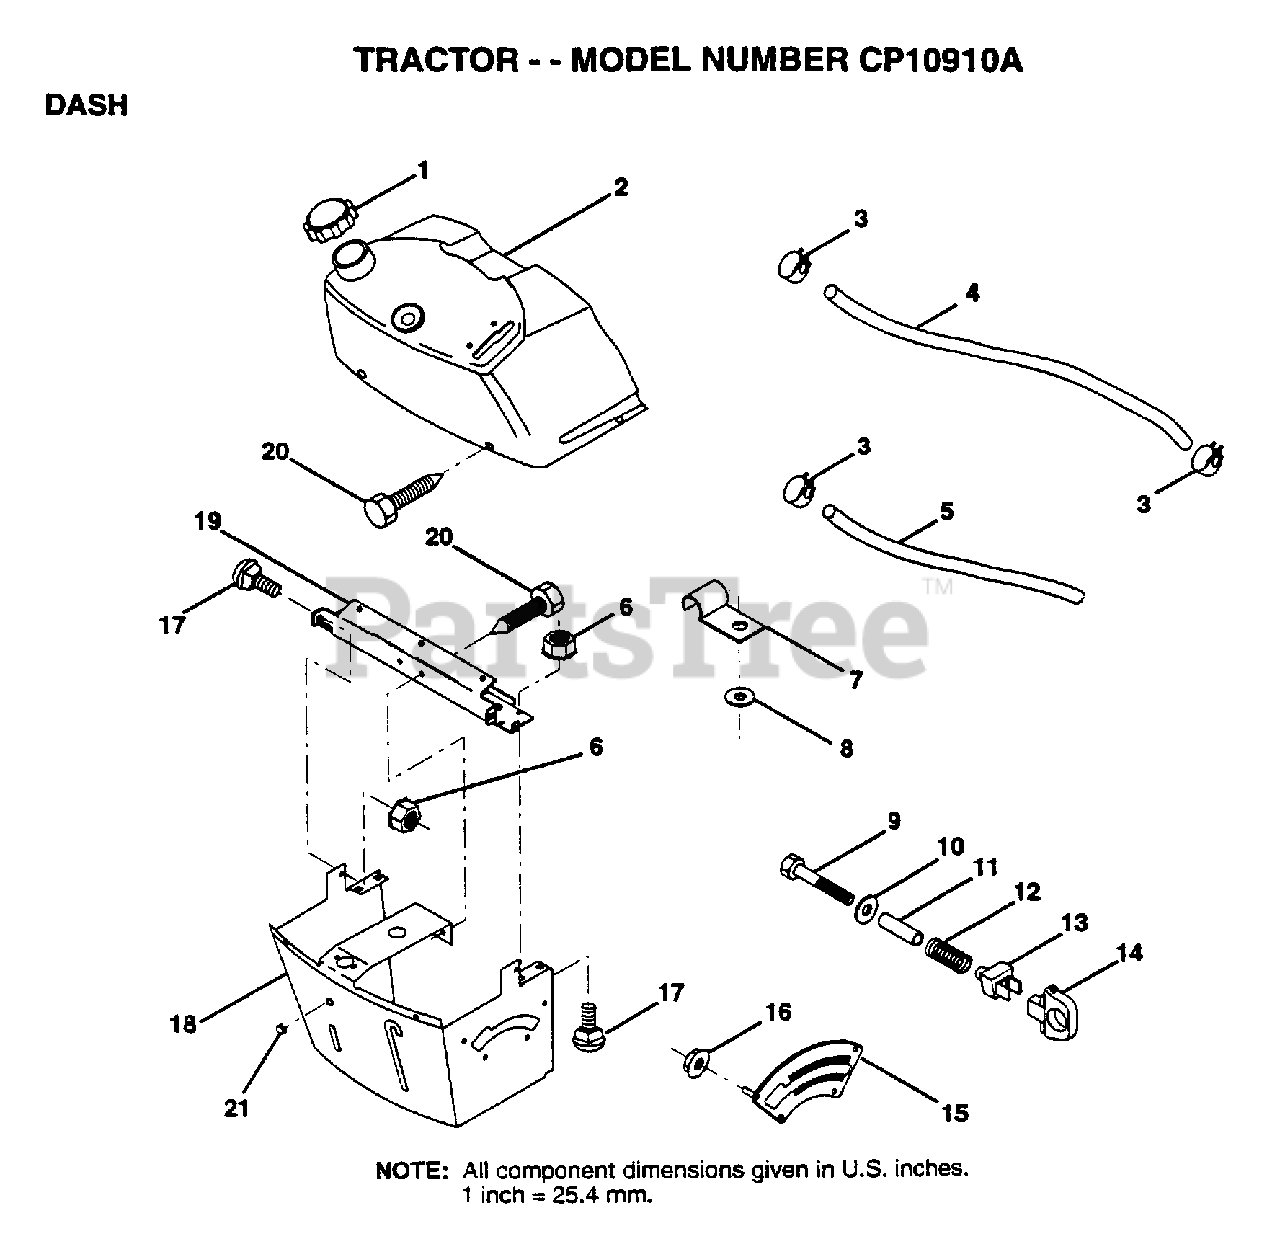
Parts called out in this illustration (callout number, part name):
1	CAP BLK FUEL LR
2	TANK.ASM.DASH.LR
3	HOSE CLAMP
5	FUEL LINE T
6	NUT HXKEP 1/4X20
7	CLIP T
8	WASHER PM
9	BOLT
11	SPACER SPLIT
12	SPRING M
13	"KNOB,HGT RETAINER"
14	KNOB
15	ADJUSTER QUAD
16	NUT
17	BOLT
18	SUPT ASSY DASH
19	CROSS BRACE
20	SCREW.1/4-20X1/2
21	PLUG DOME
